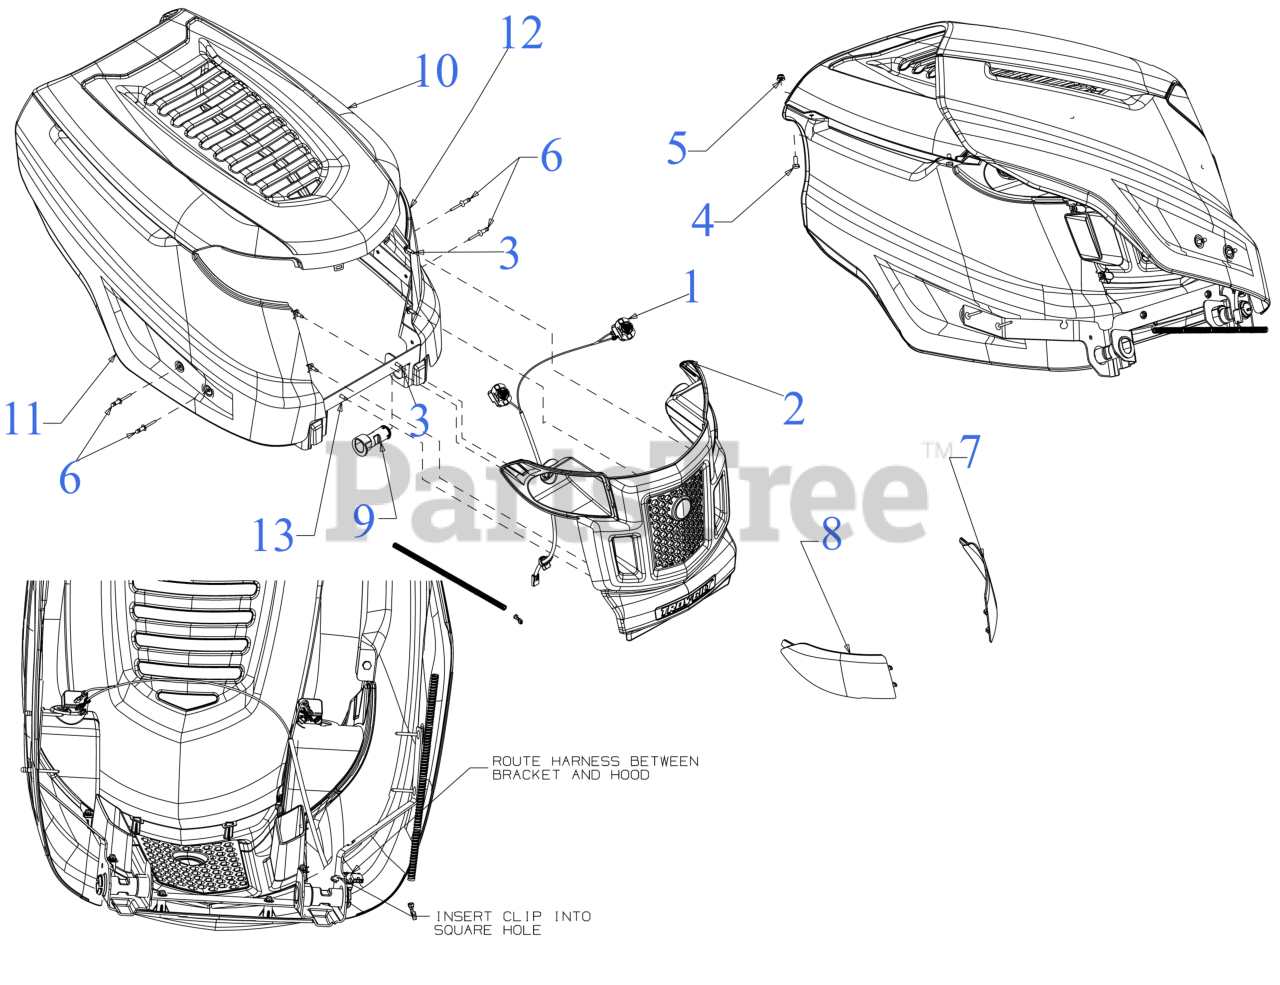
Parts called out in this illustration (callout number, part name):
1	HEADLIGHT HARNESS (LED/3PIN)
1	LED HEADLIGHT & SOCKET (150 LUMNES)
2	GRILLE ASSEMBLY (TROY-BILT)
2	LABEL-TROYBILT/GEAR
3	SCREW 1/4-10 x .750
4	SCREW 1/4-20 x .620 GR5
5	FLANGE LOCK NUT
6	POP RIVET 6.4MM x 10MM
9	HOOD PIVOT PIN
11	SIDE PANEL (RH) (K STYLE)
12	SIDE PANEL (LH) (K STYLE)
13	HOOD PIVOT BRACKET
